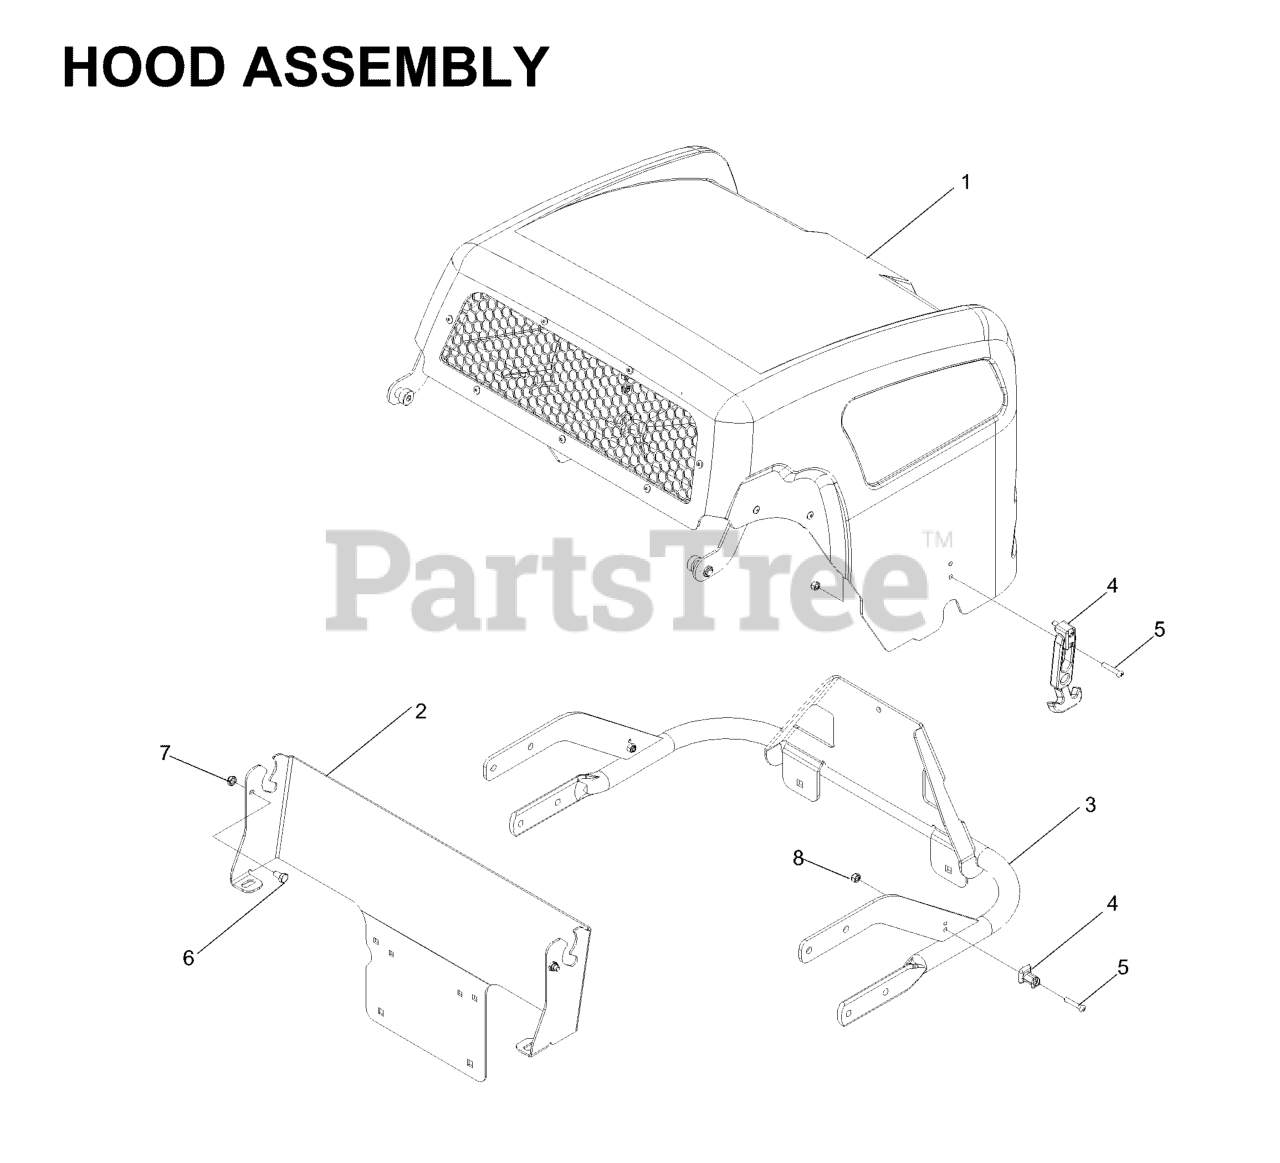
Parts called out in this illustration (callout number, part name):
1	HOOD ASSEMBLY, EZ
2	SUPPORT, HOOD
3	BUMPER WELDMENT
4	DRAW LATCH, FLEXIBLE T-HANDLE
5	SCR, #10-24 X 1-1/8
6	HCS 1/4-20.
7	JAM NUT 1/4C (2 2 PW01)
8	NUT 10-24 NYLOC
